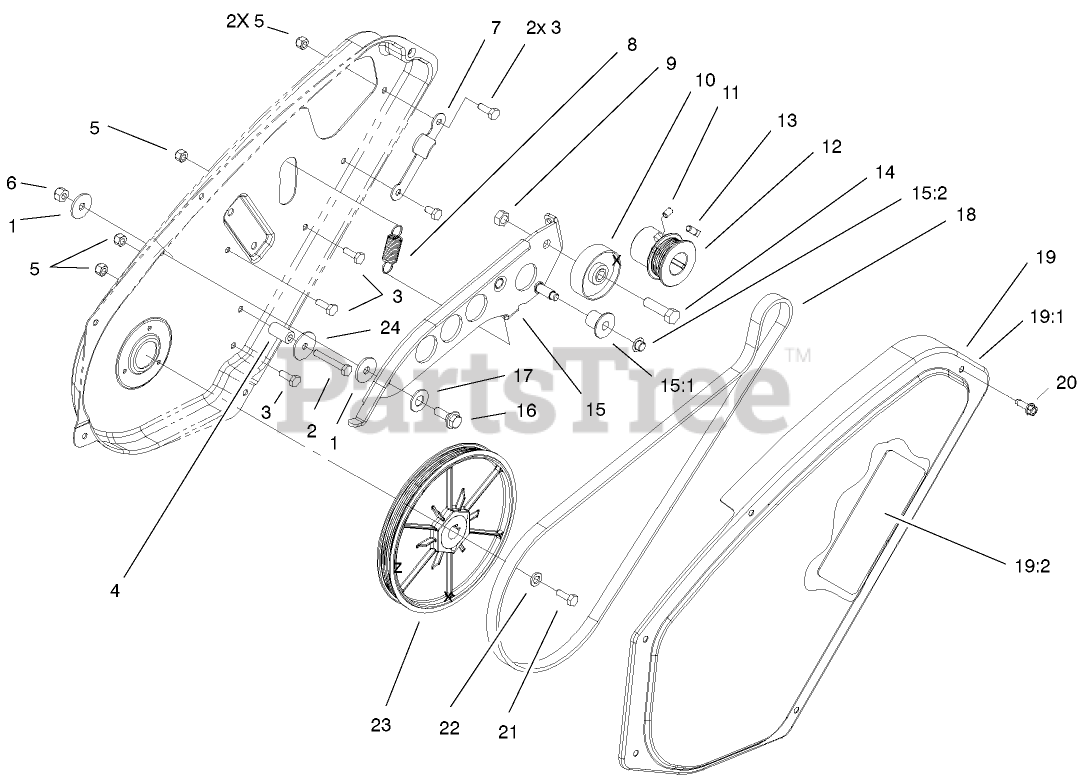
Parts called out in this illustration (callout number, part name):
1	WASHER-PIVOT
2	SCREW-HH
3	SCREW-HH
4	SLEEVE-GUIDE, BELT
5	NUT-LOCK, NI
6	NUT-LOCK, NI
7	BELT-GUIDE
8	SPRING
9	NUT-LOCK, CONE
10	PULLEY-IDLER
11	SCREW-HSH
12	SCREW-SQH
13	PULLEY
14	SCREW-HH
15	BRAKE-ARM
15:1	ROLLER-BRAKE
15:2	NUT-PUSH
16	SCREW-SHOULDER
17	WASHER
18	BELT-DRIVE
19	DRIVE COVER ASM
19:1	DECAL-WARNING
19:2	DECAL-ROUTING, BELT
20	SCREW-HWHTF
21	SCREW-HH
22	WASHER-BELLEVILLE
24	WASHER-FLAT
